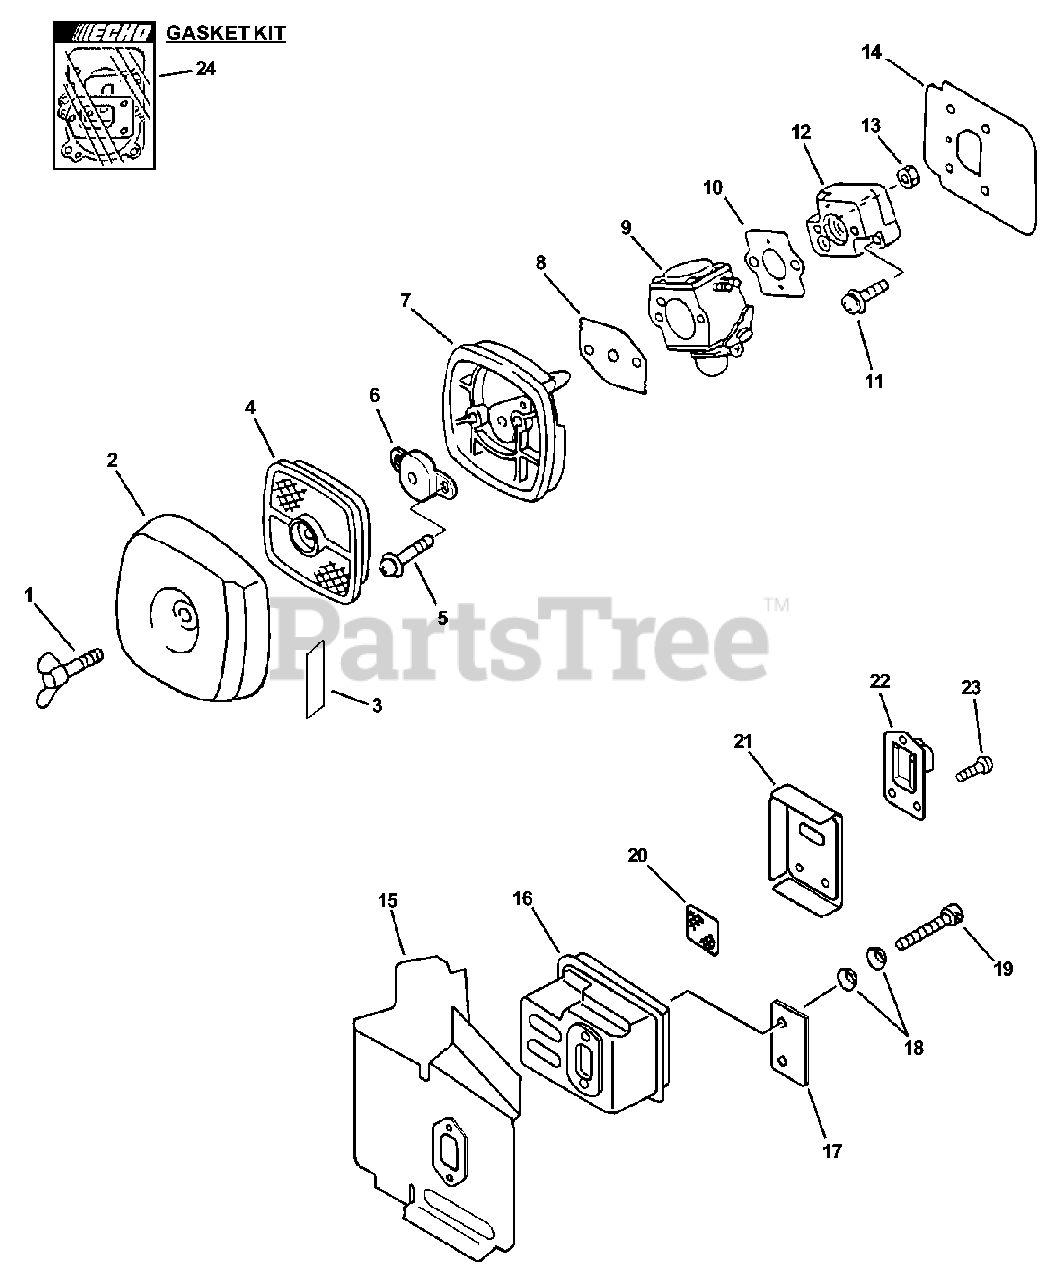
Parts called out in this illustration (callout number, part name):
1	BOLT, WING 5×20
2	COVER, AIR FILTER - GRAY
3	LABEL, CHOKE
4	FILTER, AIR - SINGLE LAYER
5	SCREW 5×65
6	PLATE, PREVENT
7	CASE, AIR FILTER - GRAY
8	GASKET, INTAKE
9	CARBURETOR - C1U-K58
10	GASKET, INTAKE
11	SCREW 5×20
12	INSULATOR, INTAKE
13	NUT M5
14	HEAT SHIELD, INTAKE
15	SHIELD, EXHAUST
16	MUFFLER
17	PLATE, EYE
18	CONICAL WASHER
19	BOLT 5×55
20	SCREEN, SPARK ARRESTER
21	GASKET, EXHAUST
22	GUIDE, EXHAUST
23	SCREW 4×12
24	GASKET KIT
